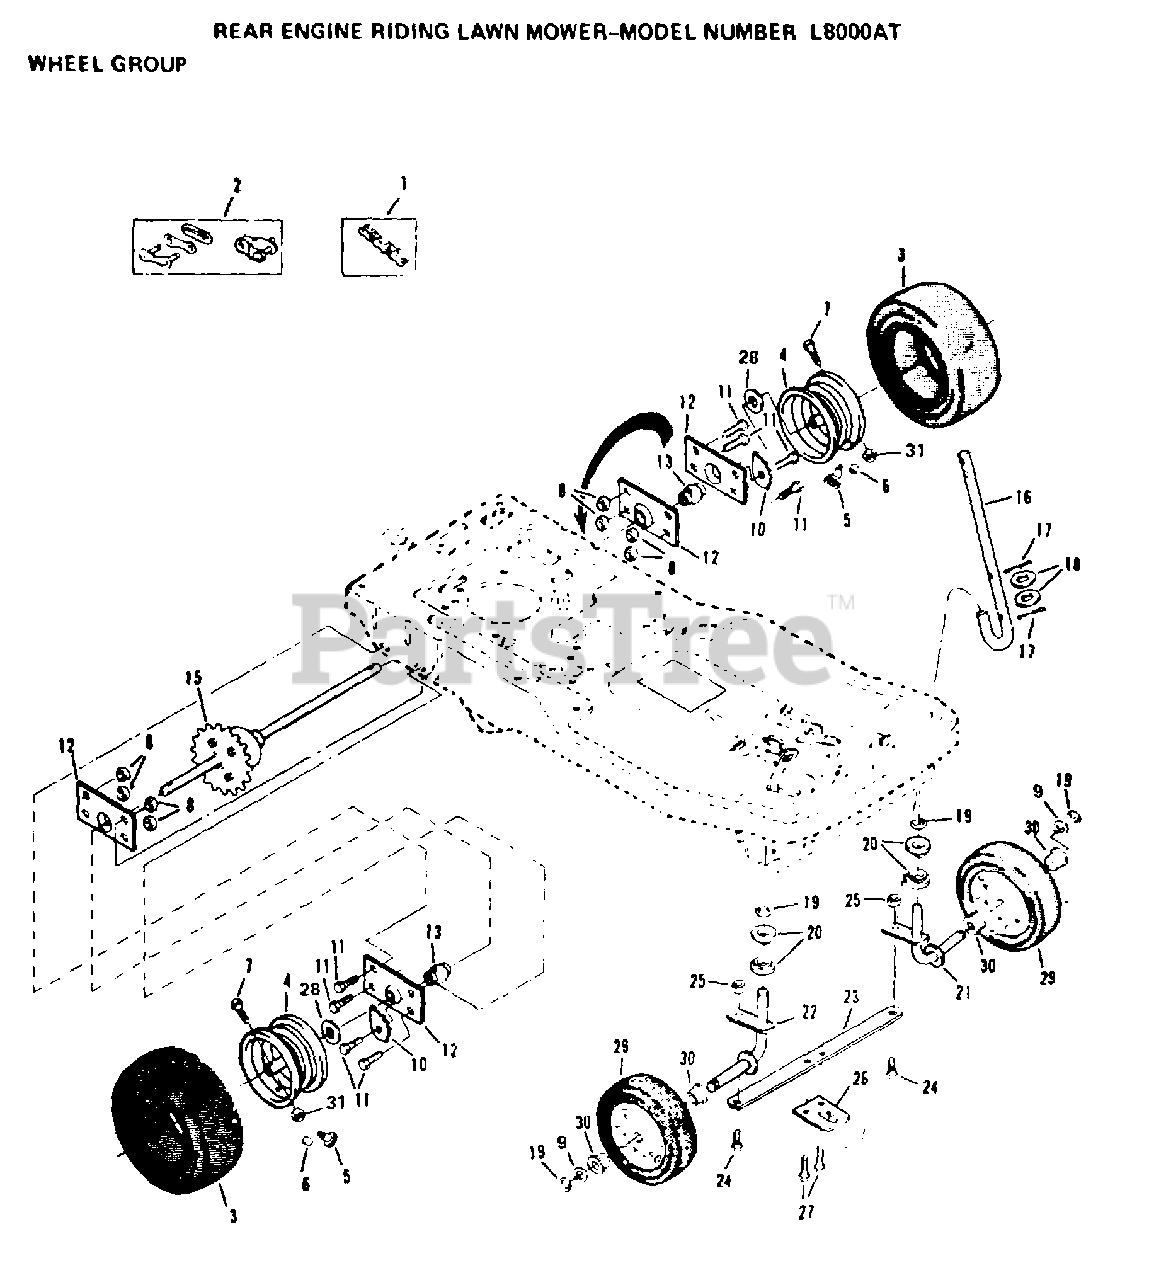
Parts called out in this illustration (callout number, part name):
1	CHAIN#41(82PITCHE
5	VALVE STEM LT
6	VALVE CAP
7	BOLT
9	WASHER.21/32X1
12	"CUP, BEARING"
13	"LT, BEARING"
16	STEERING SHAF T
17	PIN COTTER 1/8
18	WASHER D
20	BUSHING
21	KING PIN ASSY L
24	BOLT SHOULDER LT
25	NUT.LOCK.5/16-24
26	STEERING PLAT T
27	SCREW LT
